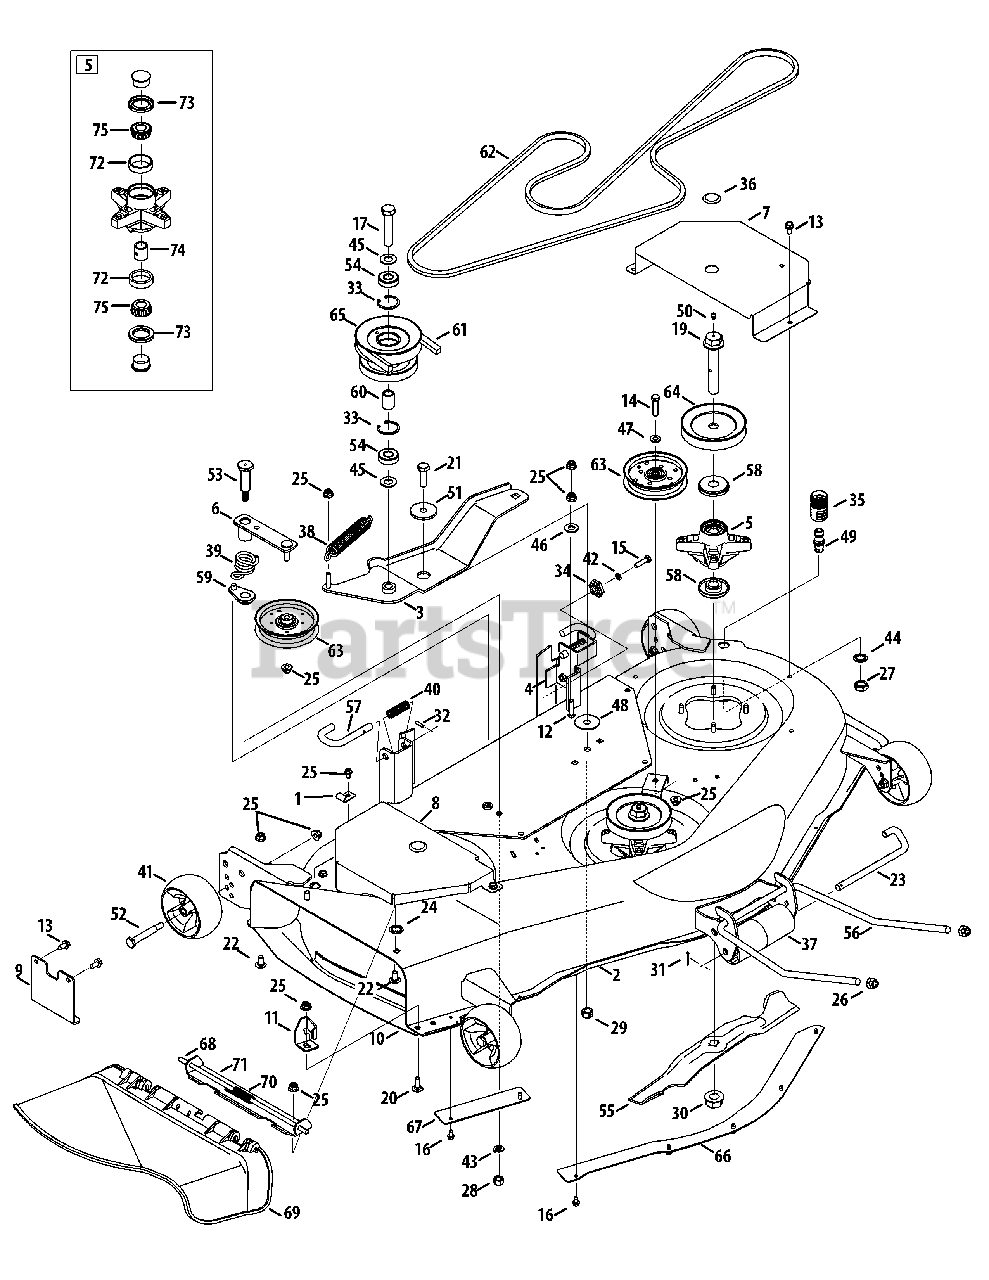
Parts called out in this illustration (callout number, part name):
1	Hook Retainer Bracket
2	Deck Assembly
3	PTO Idler Assembly
4	Hanger Adjustment Bracket
5	Spindle Assembly
6	Idler Arm Assembly
7	LH Spindle Shield
8	RH Spindle Shield
9	Up-Stop Bracket
11	Chute Deflector Stop
12	Carriage Bolt, 3/8 X 16 X 1.50
13	Hex Washer Screw, 5/16-18 x .750
14	Hex Screw, 3/8-16 x 1.50
15	Hex Screw, 5/16-18 x 1.25
16	Hex Washer Screw, 1/4-20 x .500
17	Hex Screw, 5/8-18 x 3.00
18	Hex Washer Screw, 5/16-18 x .750
19	Spindle Bolt, 3/4-16 x 4.25
20	Carriage Bolt, 3/8-16 x 1.00
21	Hex Screw, 1/2-20 x 1.50
22	Carriage Bolt, 3/8-16 x .75
23	Roller Pin, 1/2 x 7.31
24	Push Nut, 3/8
25	Flange Lock Nut, 3/8-16
26	Flex Lock Nut, 1/2-13
27	Hex Nut, M16-1.5
28	Hex Nut, 7/16-14
29	Hex Lock Nut, 1/2-20
30	Flange Lock Nut, 3/4-16
31	Cotter Pin, 3/32 x 1.25
32	Spirol Spring Pin
33	Retainer Ring
34	Deck Adjustment Gear
35	Water Nozzle Adapter
36	Button Plug
37	Front Roller
38	Extension Spring, 1.0 x 6.140
39	Idler Torsion Spring, 1.10 x 1.3
40	Compression Spring, .66 x 1.8
41	Deck Wheel, 5.0
42	Lock Washer, 5/16
43	Lock Washer, 7/16
44	Lock Washer, 5/8
45	Flat Washer, .65 x 1.25 x .075
46	Flat Washer, .510 x 1.000 x .125
47	Flat Washer, .406 x .812 x .051
48	Flat Washer, .535 x 1.92 x .060
49	Deck Water Nozzle
50	Drive Lube Fitting, 3/16
51	Shoulder Spacer, .9790 x .2025
52	Shoulder Screw, 1/2 x 2.50
53	Shoulder Screw, 7/16-14 x .68 x 2.11
54	Ball Bearing, .625 x 40 x 12
55	2-in1 Blade, QTY-3, round hole
56	Front Lift Rod
57	Mower Support Pin
58	Spindle Spacer
59	Spring Retainer
60	Spacer, .88 x .635 x 1.25
62	Deck Belt
63	Idler Pulley
64	Spindle Pulley
65	Double Pulley
68	Hinge Pin, .3175 x 14.06
69	Chute Deflector
70	Torsion Spring, .44 x 2.0
71	Chute Bracket
72	Bearing Cup, .750
74	Bearing Spacer, .78 x 1.0 x 1.0425
75	Cone Bearing, .750
